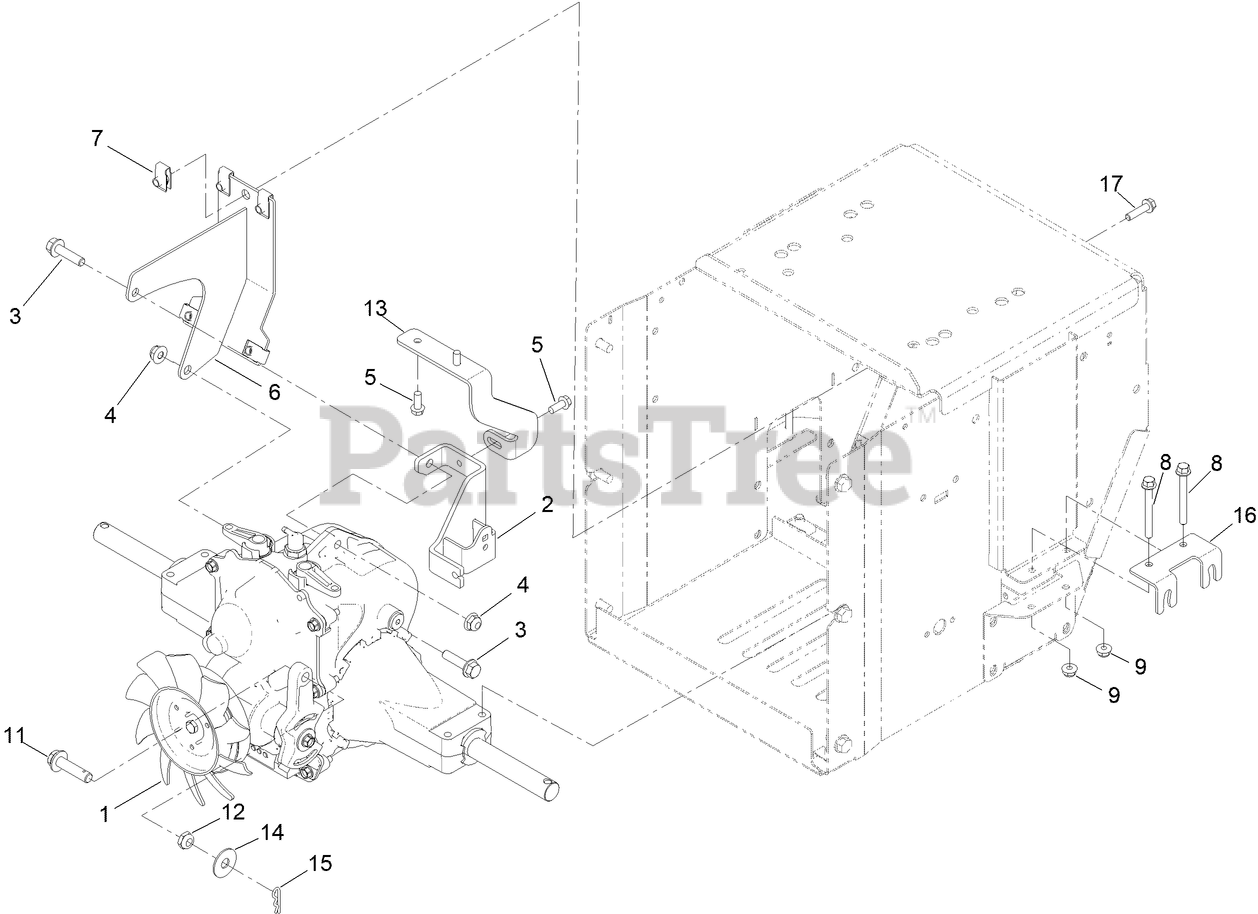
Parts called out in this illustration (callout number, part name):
1	HYDRO - SST
2	BRACKET-HYDRO, WELD ASM
3	SCREW-HHF
4	NUT-HF
5	SCREW-HWH
6	SUPPORT-HYDRO, REAR WELD ASM
8	SCREW-HHF
9	NUT-HF
11	SCREW-HHF SPCL
13	BRACKET-HYDRO, UPPER
14	WASHER-FLAT
16	STOP-CARRIER
17	SCREW-HWHTF
